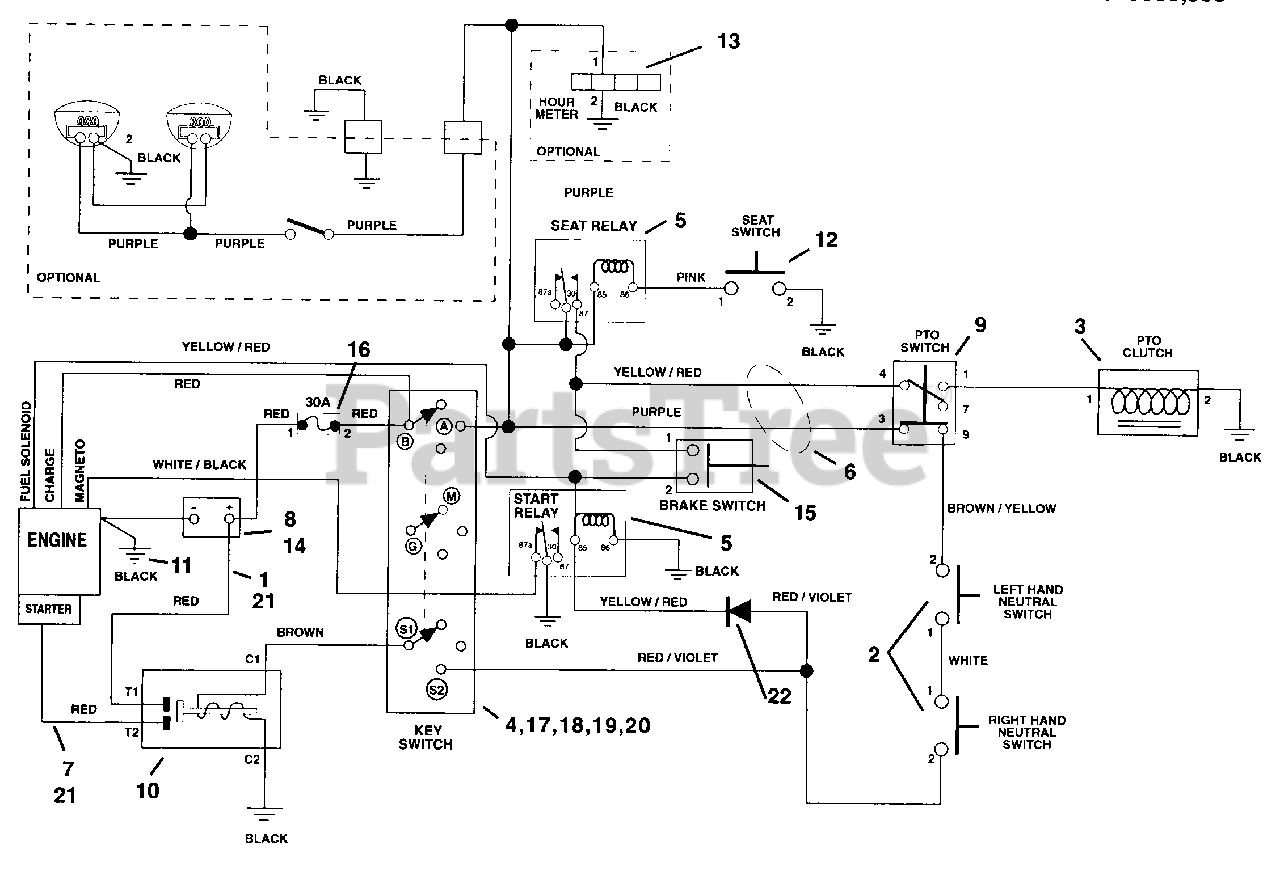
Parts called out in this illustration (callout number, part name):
1	CBL,BATTERY TO SOLENOID
2	SWITCH, NEUTRAL START N.O.
3	CLUTCH, ELECTRIC - WARNER
4	KEY SWITCH
5	RELAY
6	HARNESS, WIRE - 1648
7	START CABLE 22"
8	BATTERY W/ TUBE
9	SWITCH, CLUTCH
10	SOLENOID
11	GROUND CABLE .31X22.00X.31
12	SWITCH- SEAT
13	HOUR METER
14	RUBBER PAD
15	SWITCH- SINGLE POLE N.O.
16	30 AMP Fuse
17	KEY -W/CAP
18	CAP - IGNITION SWITCH
19	NUT- PANEL .562-24 GRECO
20	WSHR-LK-INT .563X.040 PL
21	BOOT, INSULATOR
22	MOLDED DIODE PLUG 1 AMP
